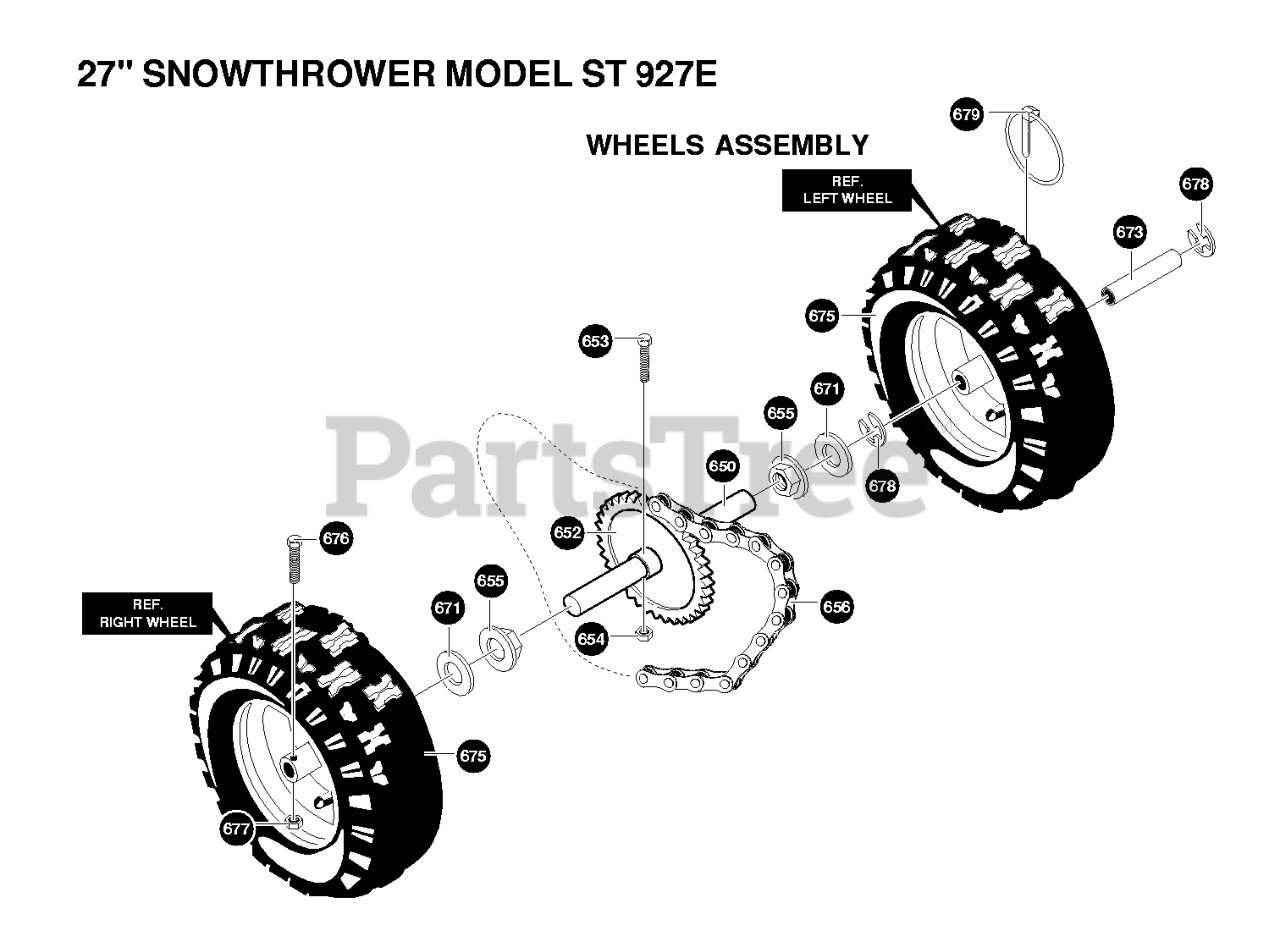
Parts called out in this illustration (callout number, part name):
650	SHAFT, AXLE
652	SPROCKET, HUB #40-35TX.74ID
654	NUT, 1/4-20 REGHEXCTRLK
655	FLANGE BEARING
656	CHAIN, ROLLER #42X40 PITCH
673	BUSHING, WHEEL 4" LG
675	TIRE & RIM, PU 16X4.8X4
677	NUT, 1/4-20 REGHEXCTRLK
678	RETAINER RING
